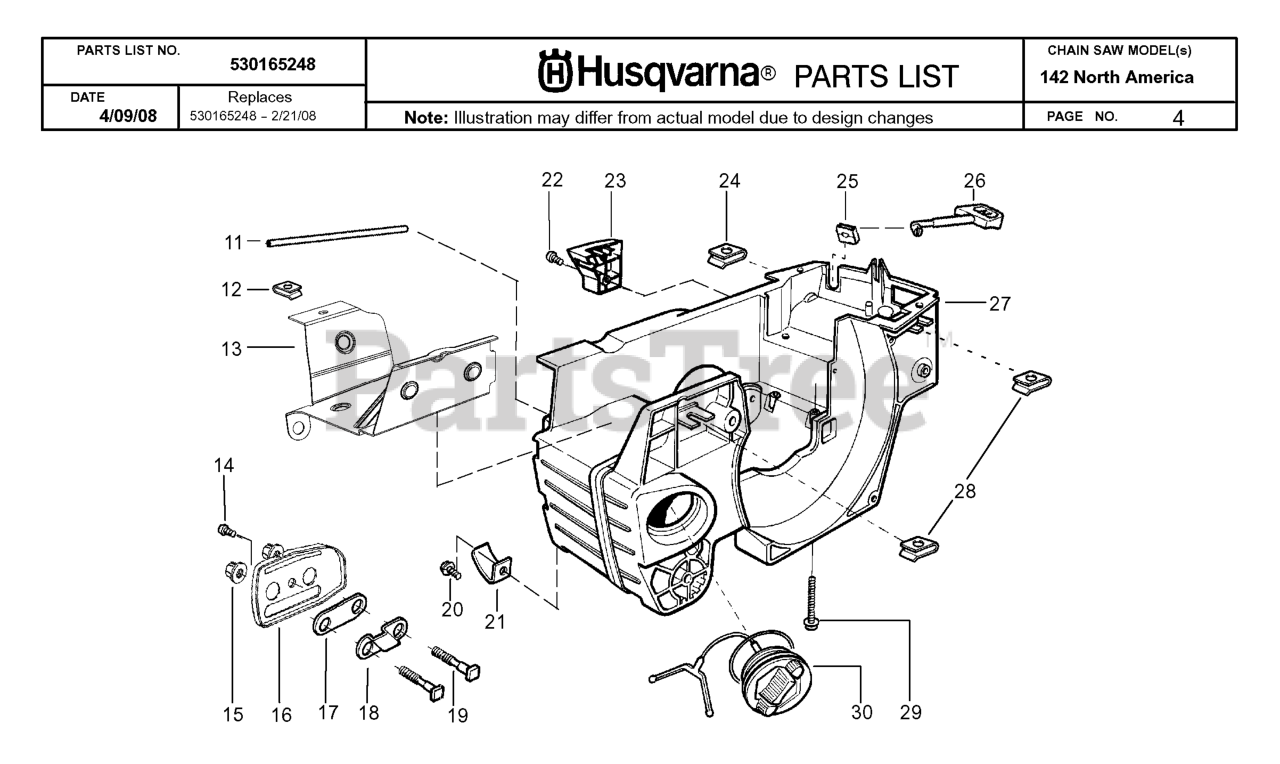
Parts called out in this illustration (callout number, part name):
13	HEATSHIELD, LOWER
17	OIL TANK GASKET
18	PLATE,BAR MOUNT
19	BAR BOLT 36/41
21	CHAIN CATCHER 36/41
23	LIMITER COVER
25	CHOKE GUIDE 36/41
26	CHOKE 36/41
27	KIT ASSY CHASSIS
29	SCREW M5-0.8X35M TAP
